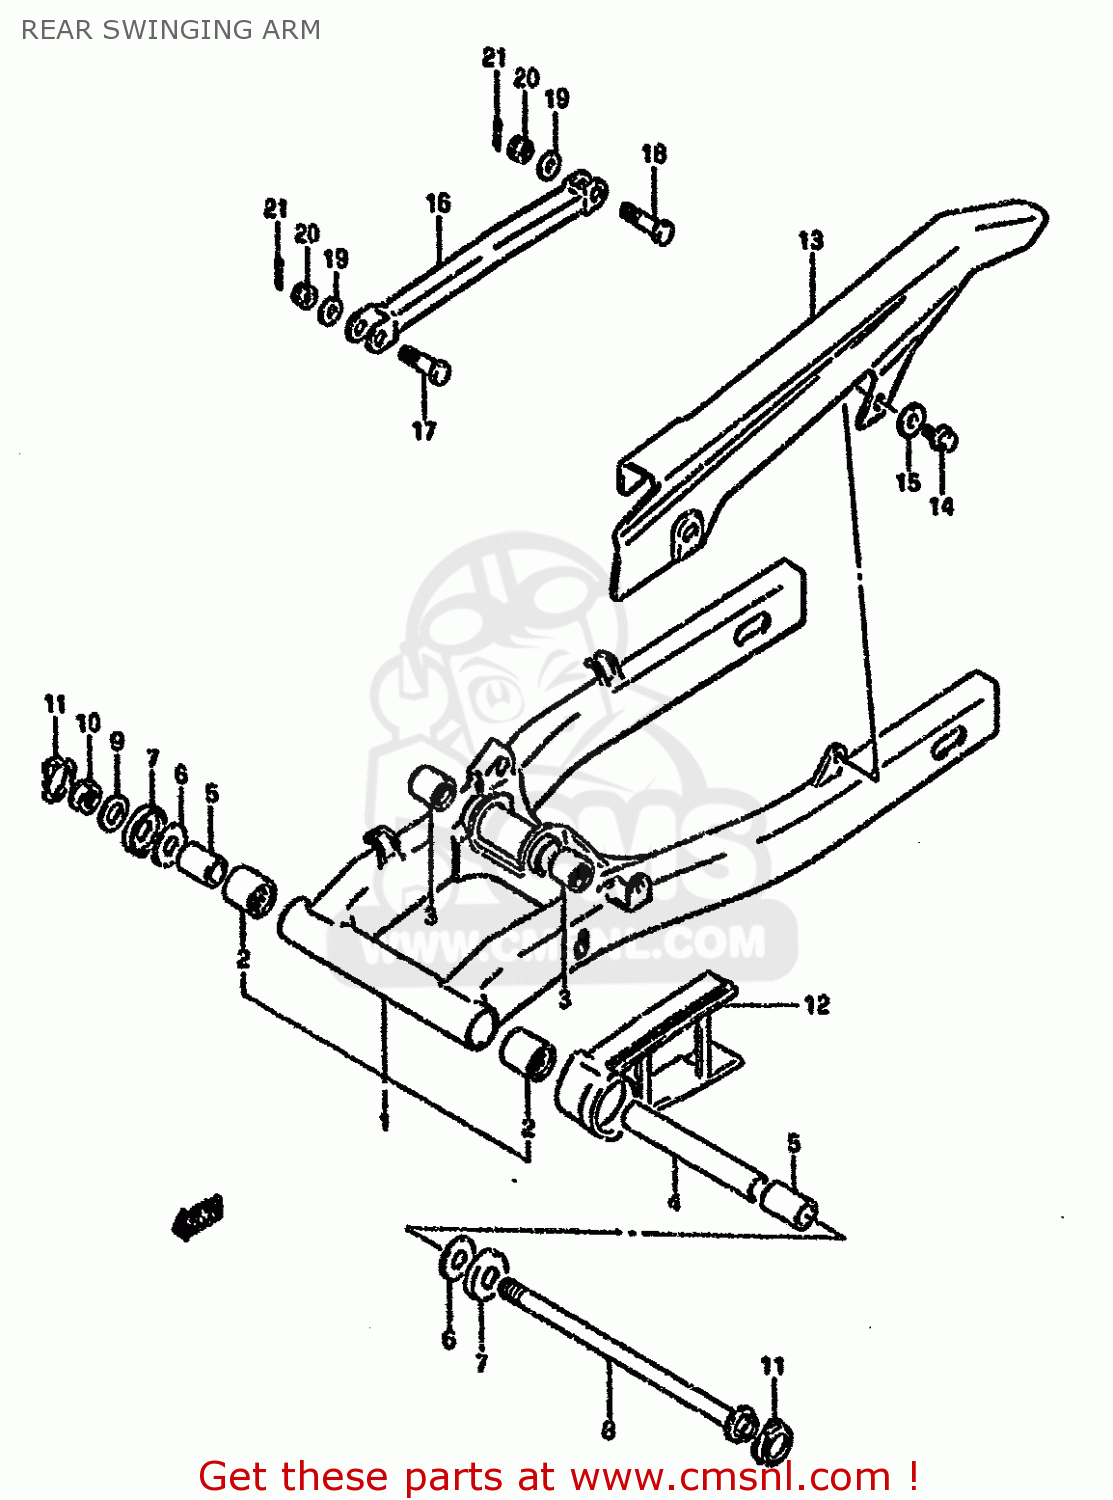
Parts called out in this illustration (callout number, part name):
1	SWING ARM ASSEMBLY,REAR
2	BEARING(22X29X30)
3	BEARING(17X24X25)
4	SPACER,RR SWGARM PIVOT CTR
5	SPACER,RR SWGARM PIVOT
6	WASHER(14.2X34X1)
7	CVR,RR SWGARM DUST SEAL(OD:40)
8	SHAFT,RR SWINGINGARM PIVOT
9	WASHER(14.5X29X2.3)
10	NUT
11	CAP,RR SWINGING ARM PIVOT
12	BUFFER,CHAIN TOUCH DEFENSE
13	CASE,CHAIN
14	BOLT
15	WASHER
16	TORQUELINK,RR
17	BOLT(10X41)
18	BOLT(10X35)
19	WASHER (10X18X3.2)
20	NUT
21	PIN 20X20
